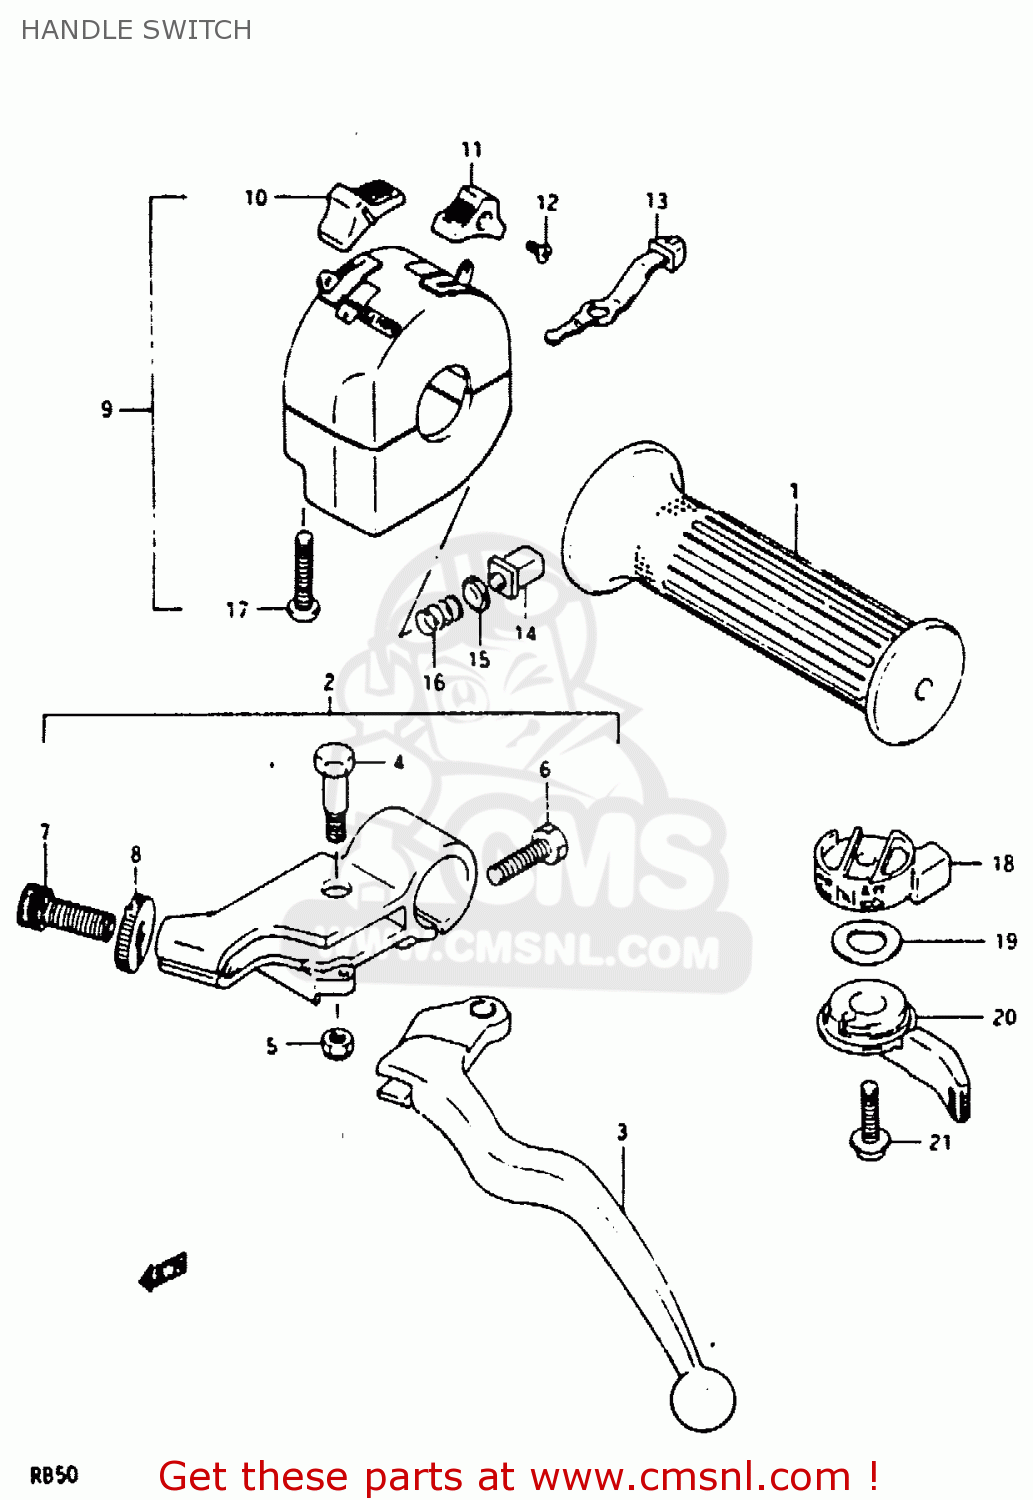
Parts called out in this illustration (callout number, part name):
1	GRIP,LEFT
2	LEVER ASSY,CLUTCH
3	LEVER,CLUTCH
4	BOLT,LEVER
5	NUT
6	BOLT 6X20
7	ADJUSTER,CABLE
8	NUT,CABLE ADJUSTER LOCK
10	KNOB,LIGHTING SWITCH
11	KNOB,DIMMER SWITCH
12	SCREW
13	KNOB,TURNSIGNAL
14	BUTTON,HORN
15	CONTACT
16	SPRING
17	SCREW
18	BODY,CHOCK
19	WASHER,ADJUSTER
20	LEVER,STARTER
21	SCREW
